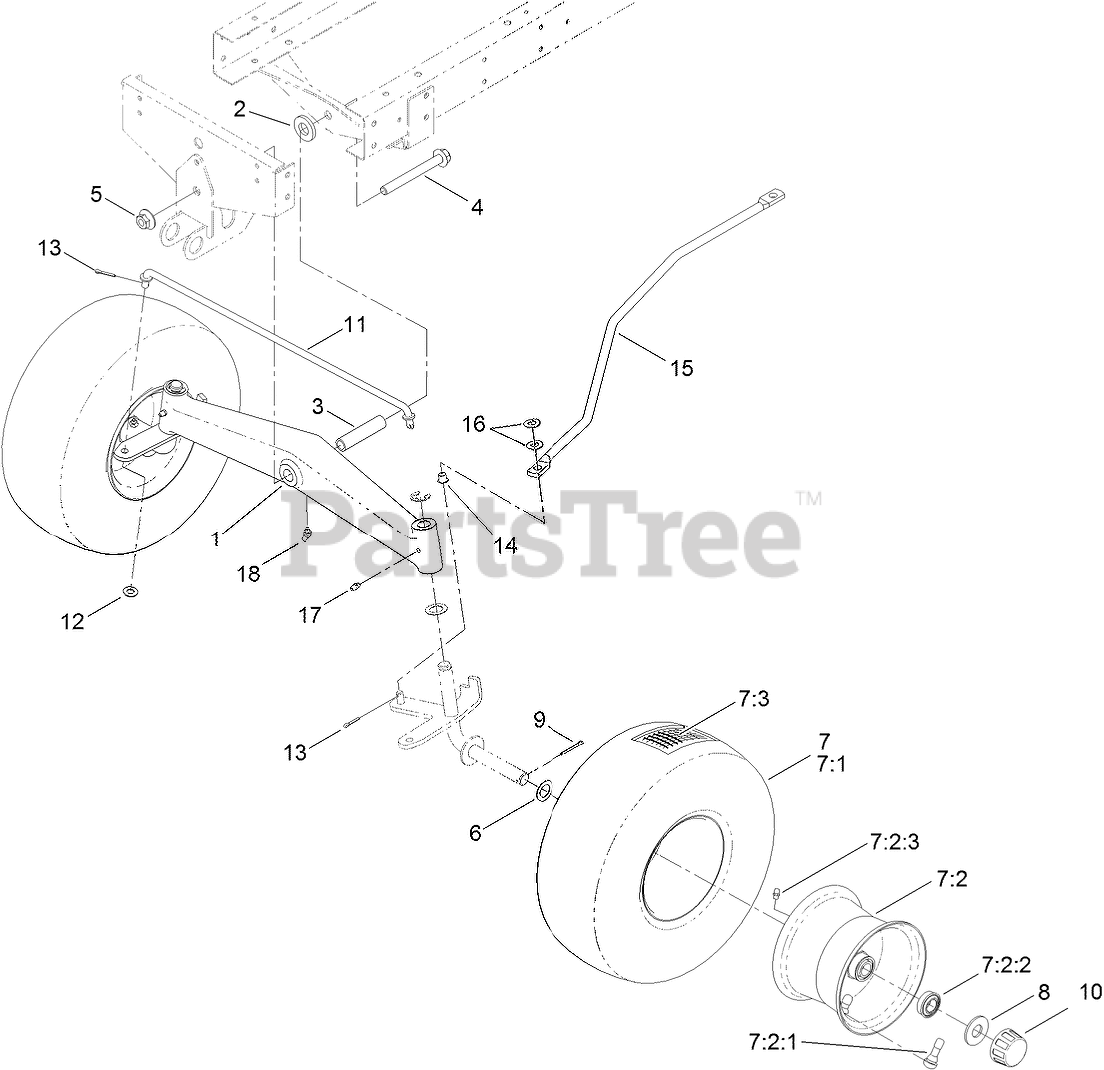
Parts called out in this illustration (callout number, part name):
1	FRONT AXLE ASM
2	BUSHING-FRONT, AXLE
3	TUBE-FRONT, AXLE
4	SCREW-HHF
5	NUT-HF
6	WASHER-THRUST
7	WHEEL AND TIRE ASM
7:2:1	STEM-VALVE
7:2:2	BEARING-WHEEL
7:2:3	FITTING-GREASE
7:3	TUBE-INNER
8	WASHER-PLAIN
9	PIN-COTTER
10	CAP-HUB
11	TIE ROD-STEERING
12	WASHER-FLAT
13	PIN-COTTER
14	BUSHING-FLANGED, NYLON
15	LINK-DRAG
16	WASHER-FLAT
17	FITTING-GREASE
18	FITTING-LUBE, 45 DEG
